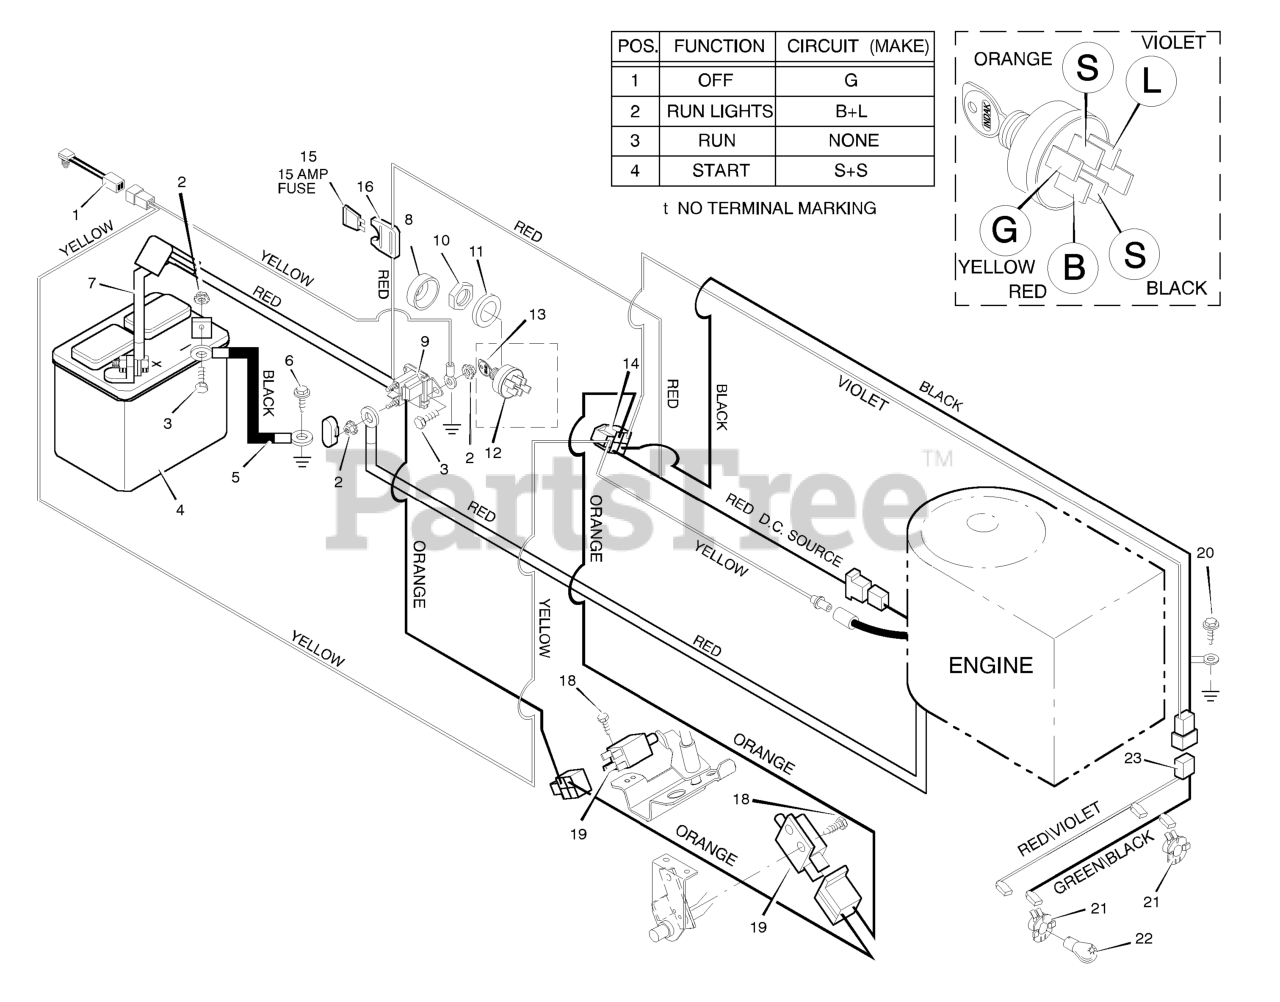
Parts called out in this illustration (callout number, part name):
1	Switch, Seat Sensor
2	Locknut
3	Bolt, Hex
4	Battery
5	Cable, Battery Ground
7	Cable, Red Battery
8	Cap, Ignition
9	Solenoid
10	Nut
12	Switch, Ignition
13	Key, Ignition
14	Harness, Chassis Wire
16	Holder, Fuse
19	Switch, Clutch
20	Screw
21	Socket, Light
22	Bulb, Light
23	Harness, Light Wire
24	Cover, Terminal
